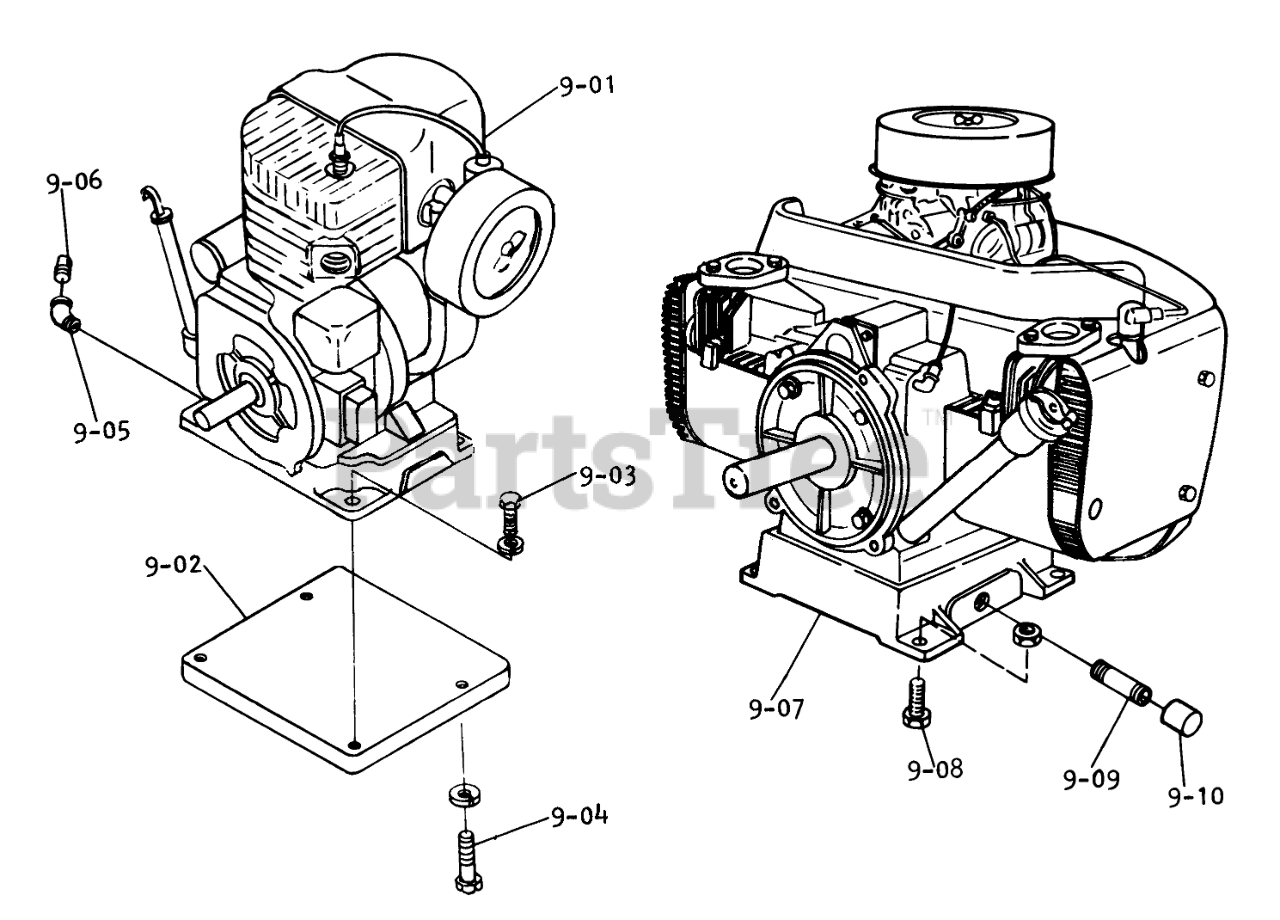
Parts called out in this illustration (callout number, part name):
9-01	Engine, 16 HP Kohler K341S-71141A
9-02	Engine Base, D-160
9-03	Bolt
9-04	Bolt
9-05	STREET ELBOW 45DEGRE
9-06	Plug
9-07	Engine, 18 HP Kohler K482S-35222B
9-08	Hhcs
9-09	Nipple 3/4 Pipe X2
9-10	Cap-3/4 Pipe
